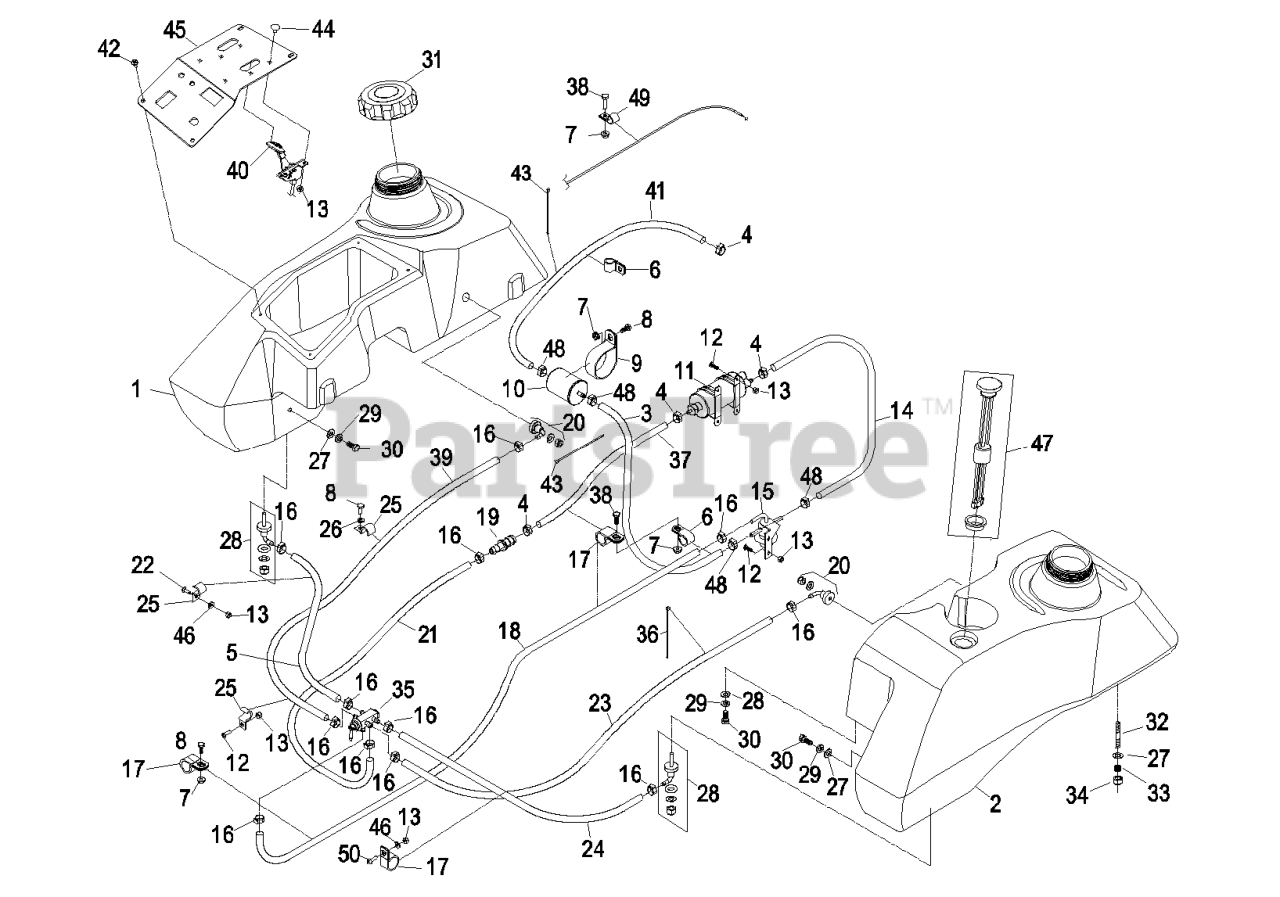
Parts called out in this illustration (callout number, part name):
3	Kit, Fuel Line W/Clamps
4	CLAMP-HOSE, FUEL
5	HOSE-FUEL
6	CLIP-LOOM
8	SCREW-HH
9	CLIP-LOOM
10	Kohler Part No 24 050 03 Fuel Filter
11	Kohler Part No 393 20 Fuel Pump
12	SCREW-PPH
13	NUT-LOCK, NI
14	KIT,FUEL LINE EFI PUMP-RE
15	Kohler Part No 24 403 17 Fuel Regulator
16	CLAMP-HOSE, FUEL
17	CLIP-LOOM
18	HOSE-FUEL
19	CONNECTOR
20	FITTING-FUEL, BULKHEAD
21	HOSE-FUEL
22	BOLT-CARR
23	HOSE-FUEL
24	HOSE-FUEL
25	CLIP-HALF, LOOM
26	WASHER-LOCK
27	WASHER-PLAIN
28	FITTING-FUEL, BULKHEAD
29	WASHER-LOCK
30	SCREW-HH
31	CAP-FUEL, GAS
32	STUD
33	SPRING-TANK, FUEL
34	NUT-LOCK, NI
35	VALVE-FUEL, DUAL FLOW
36	TIE-CABLE
37	HOSE-FUEL
38	SCREW-HH
39	HOSE-FUEL
40	CONTROL-THROTTLE
41	Kit, Fuel Line W/Clamps
42	SCREW-PPH
43	TIE-PLASTIC
44	BOLT-CARR
45	PANEL,CONTROL W/DECALS
46	WASHER-FLAT
47	Kit, Gauge Fuel
48	CLAMP
49	CLIP-LOOM
50	SCREW-HEAD, TRUSS
